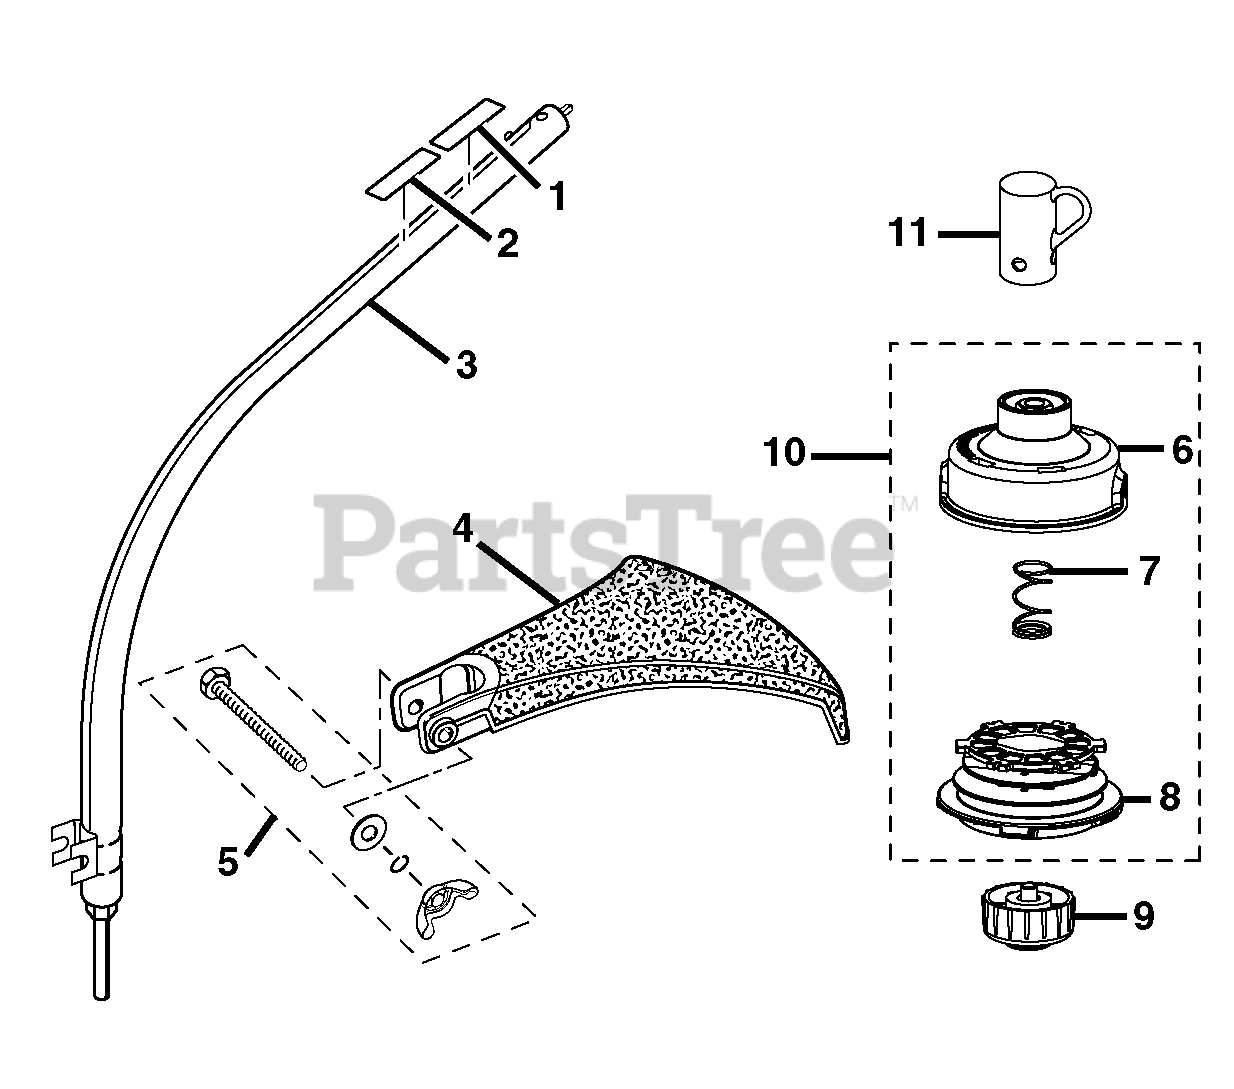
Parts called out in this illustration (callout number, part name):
1	Warning Label
2	Logo Label
3	Curved Shaft Assembly
4	Curved Shaft Grass Deflector
5	Washer and Bolt Assembly
6	String Head Housing
7	Spring
8	Spool
9	Spool Retainer
10	String Head Assembly (Incl. Key Nos. 7-9)
11	Hanger Cap
